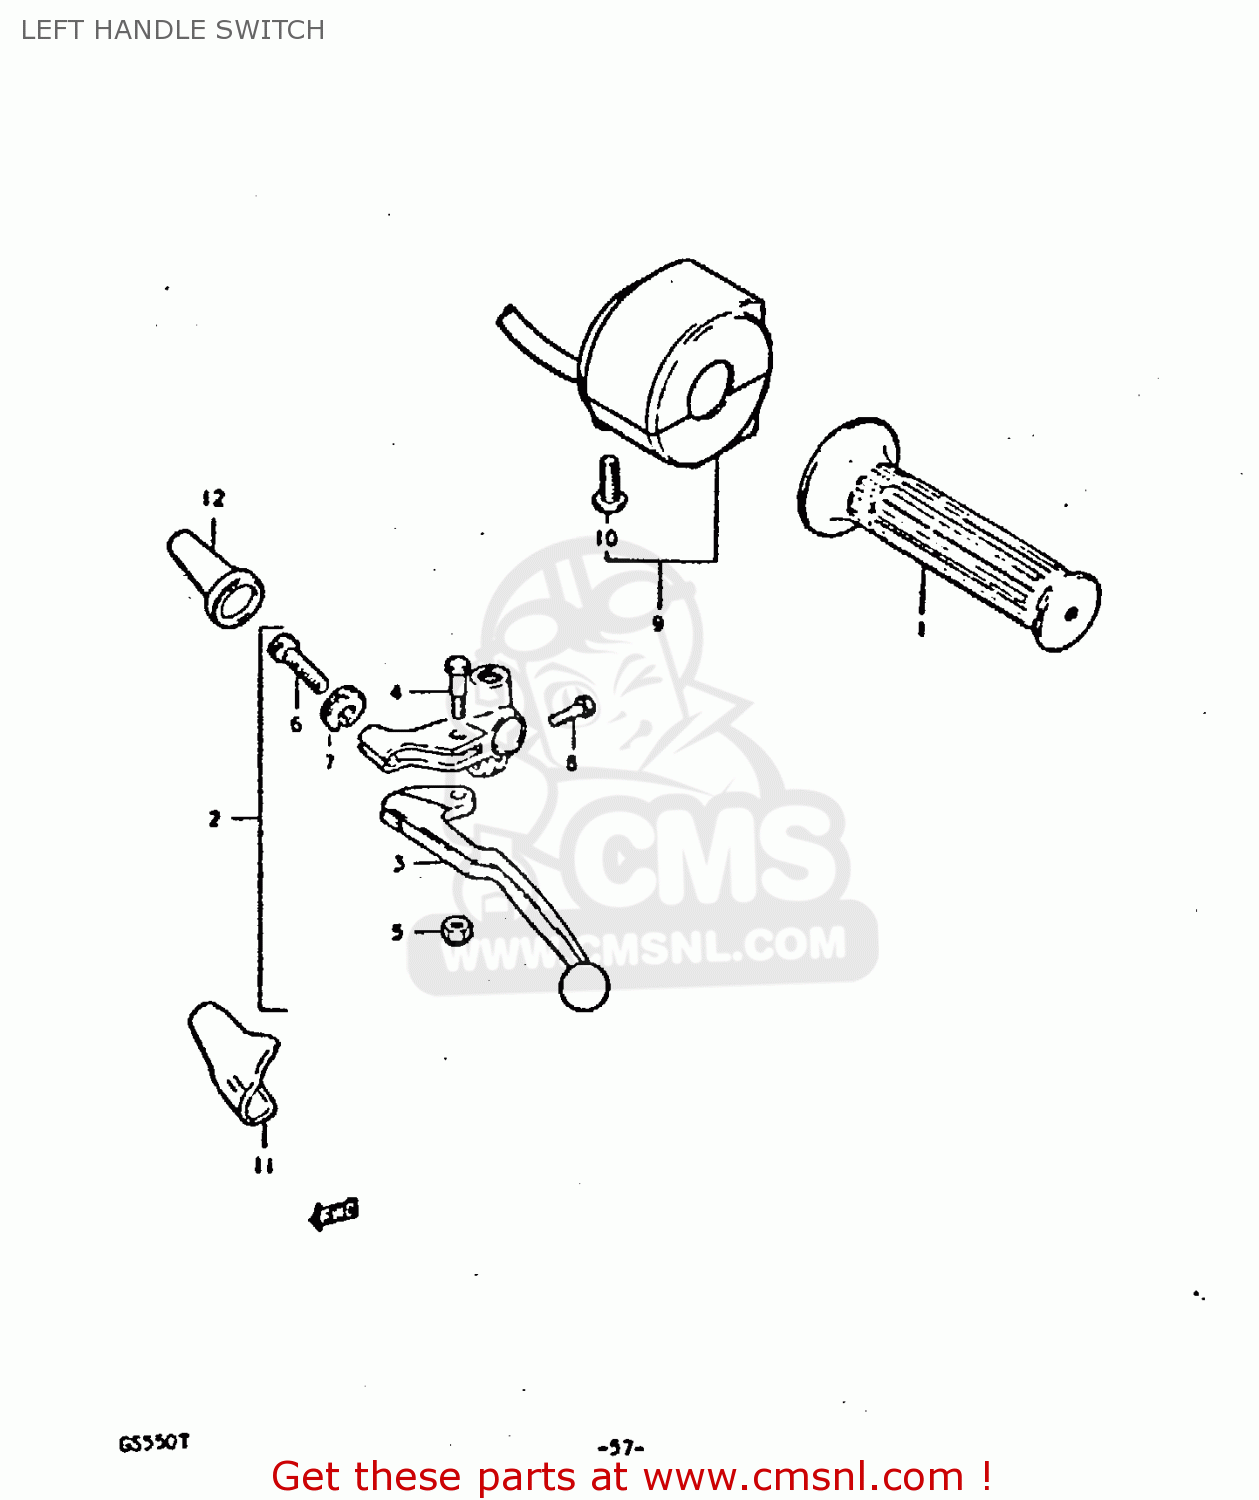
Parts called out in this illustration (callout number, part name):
1	GRIP,LEFT
2	LEVER ASSEMBLY
3	LEVER,CLUTCH
4	BOLT,LEVER
5	NUT 6MM
6	ADJUSTER,CABLE
7	NUT,CABLE ADJUSTER
8	BOLT
9	SWITCH ASSY, HANDLE LH
10	SCREW
11	COVER,CLUTCH LEVER
12	BOOT,CLUTCH CABLE
